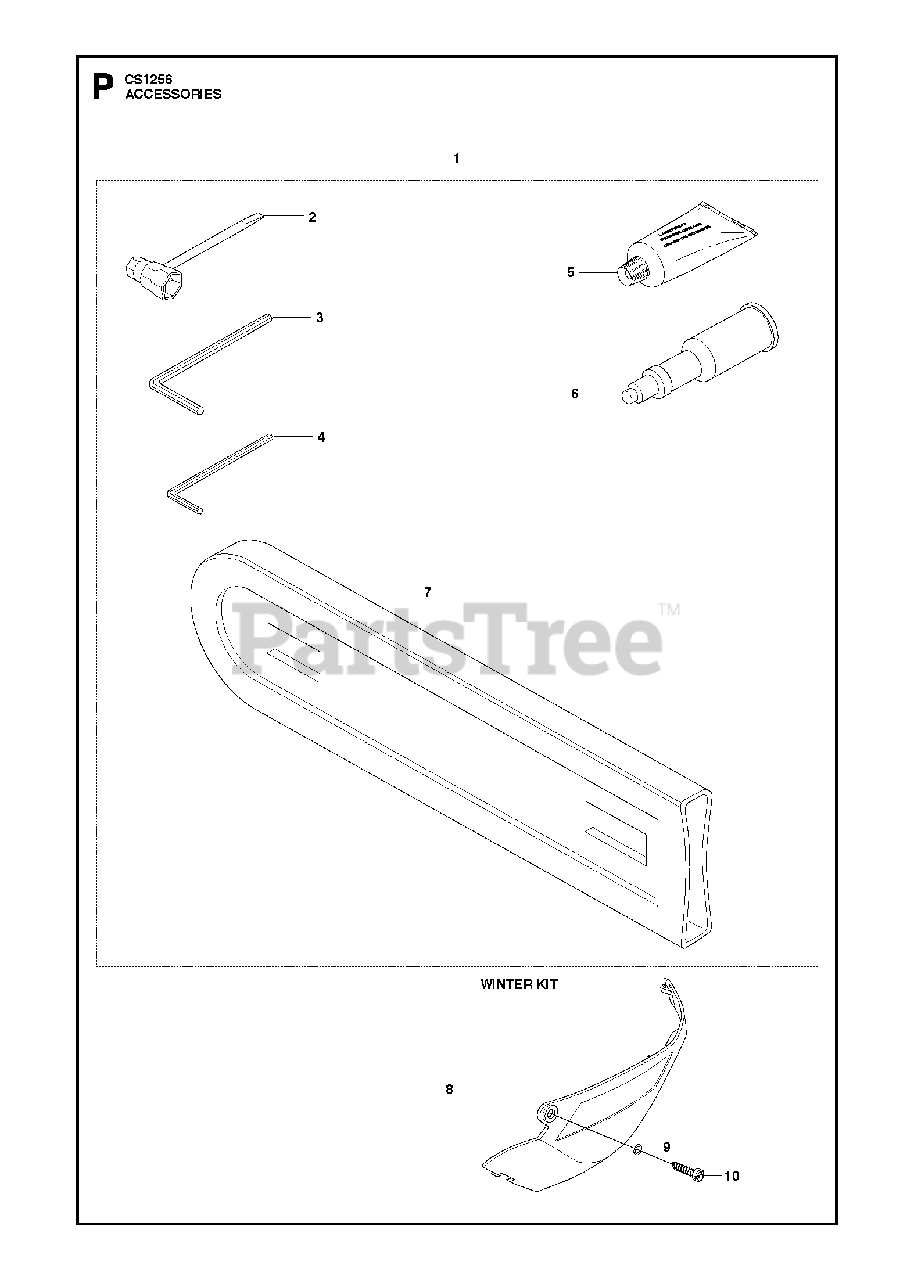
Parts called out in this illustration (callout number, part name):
1	TOOL KIT
2	COMBI TOOL
3	L-SPANNER
4	L-SPANNER
5	GREASE
6	GREASE GUN
7	BAR COVER
8	WINTER SET
9	O-RING
10	SCREW
